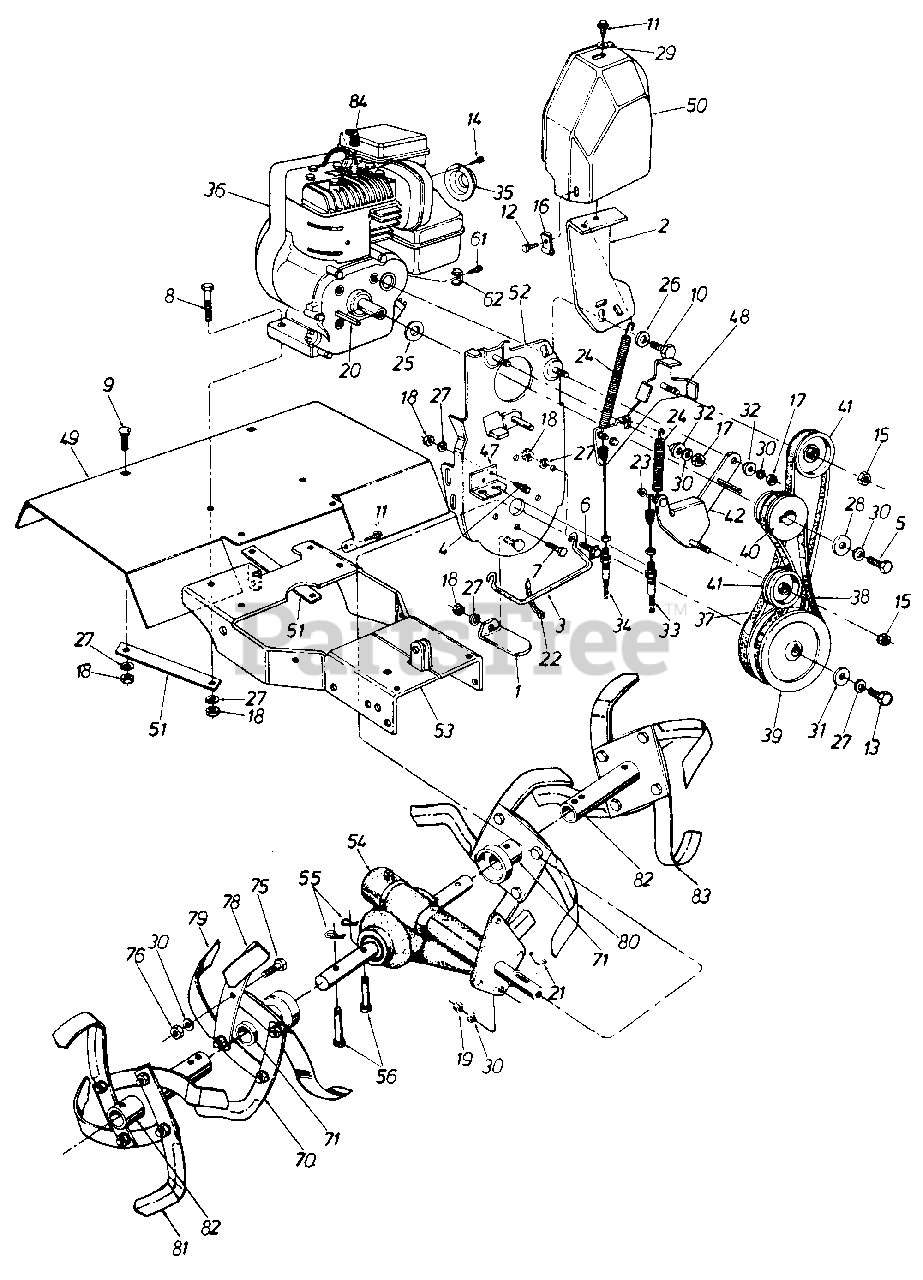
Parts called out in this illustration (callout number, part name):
1	Belt Guard
2	Bracket
3	Belt Retainer
4	Hex Bolt 5/16-18 x .75" Lg.
5	Hex Bolt 3/8-24 x 1.25" Lg.
6	Hex Sems Scr. 5/16-18 x .75" Lg.
7	Hex Bolt 3/8-16 x 1.25" Lg.
8	Hex Bolt 5/16-18 x 1.75" Lg.
9	Carr. Bolt 5/16-18 x .75" Lg.
10	Hex Bolt 5/16-24 x .75" Lg.
11	Hex TT-Tap Scr. 1/4-20 x .5"
12	Hex TT-Tap Scr. 1/4-20 x .75" Lg.
13	Hex L-Scr. 5/16-18 x 1.0" Lg.
14	Hex Wash. Hd. Sloted Scr. #8-32 x .38" Lg.
15	Hex Ins. L-Nut 3/8-24 Thd.
16	Speed Nut 1/4-20 Thd.
17	Hex Nut 3/8-24 Thd.
18	Hex Nut 5/16-18 Thd.
19	Hex Nut 3/8-16 Thd.
20	Sq. Key 3/16 x 1.0"
21	#9 Hi-Pro Key 3/16 x 3/4"
22	Cable Tie
23	Cap Speed Nut 1/4 Rod
24	Extension Spring 3-518" Lg.
25	Fl-Wash. 3/4" I.D. x 1.5" O.D.
26	L-Wash. 5/16" I.D.
27	L-Wash. 5/16" I.D.
28	Fl-Wash. .406" x 1.25" x .10"
29	Fl-Wash. .281 I.D. x .50 O.D. x .063"
30	L-Wash. 3/8" I.D.
31	Fl-Wash. .344" x 1.125" x .125"
32	Shoulder Spacer
33	Clutch Control Cable
34	Clutch Control Cable
35	Muffler Deflector
37	V-Belt 44" Lg.
38	V-Belt 37" Lg.
39	Transmission Pulley
40	Engine PuUey
41	Fl-ldler Pulley
42	Tine Idler Brkt. Ass'y.
47	Clutch Cable Bracket
48	Idler Bracket Ass'y.
49	Tine Shield
50	Belt Guard
51	Brkt. Tine Shield Reinforcement
52	Mounting Plate Ass'y.
53	Tiller Frame Ass'y.
54	Transmission Ass'y. Comp.
55	Internal Coter Pin
56	Clevis Pin
61	Hex Sems Scr. #10-32 x .62" Lg.
62	Casing Clamp
70	Inner Tine Adapter Ass'y. Comp. L.H.
71	Inner Tine Adapter Ass'y.
75	Hex Bolt 3/8-24 x 1.25" Lg.
76	Hex Nut 3/8-24
81	Outer Tine Adapter Ass'y. Comp. L.H.
82	Outer Tine Adapter Ass'y.
83	Outer Tine Adapter Ass'y. Comp. R.H.
84	Spark Plug Boot
